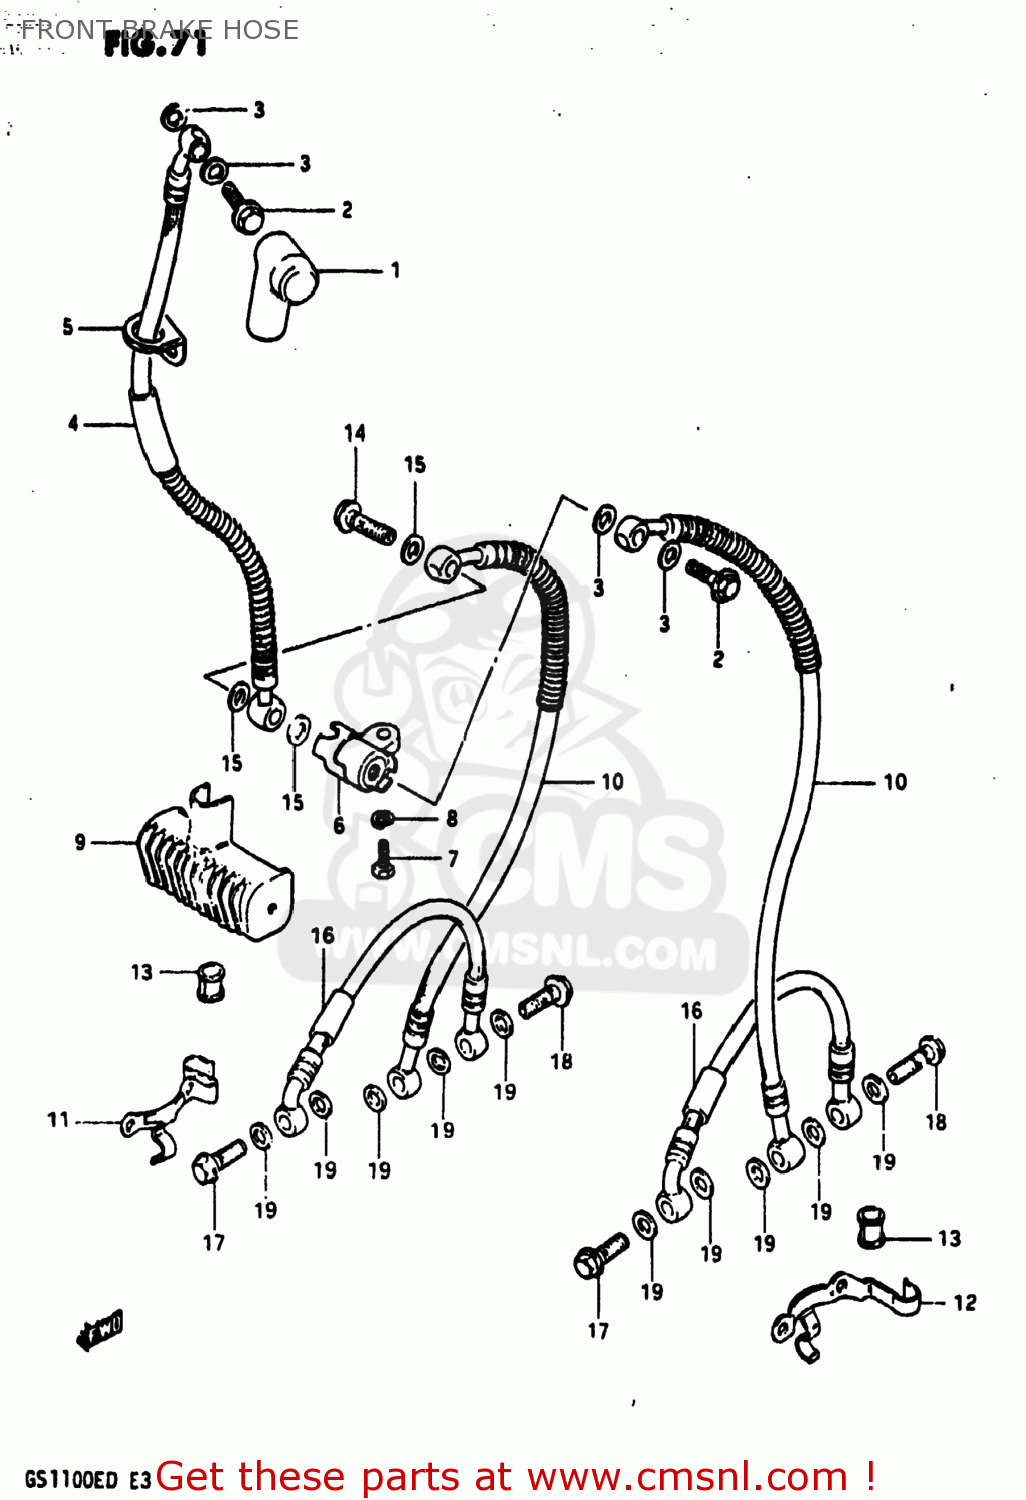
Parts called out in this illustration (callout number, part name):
1	BOOT,MASTER CYLINDER
2	BOLT,UNION
3	WASHER
4	HOSE,FRONT BRAKE
5	GUIDE,BRAKE HOSE NO.1
6	JOINT,BRAKE HOSE
7	BOLT
8	LOCK WASHER
9	COVER,BRAKE HOSE JOINT
10	HOSE,FRONT BRAKE
11	CLAMP,BRAKE HOSE,RIGHT
12	CLAMP,BRAKE HOSE,LEFT
13	BUSH,BRAKE HOSE GUIDE,NO.2
14	BOLT,UNION
15	WASHER
16	HOSE,ANTI-NOSE DIVE
17	BOLT UNION
18	BOLT,UNION
19	WASHER
